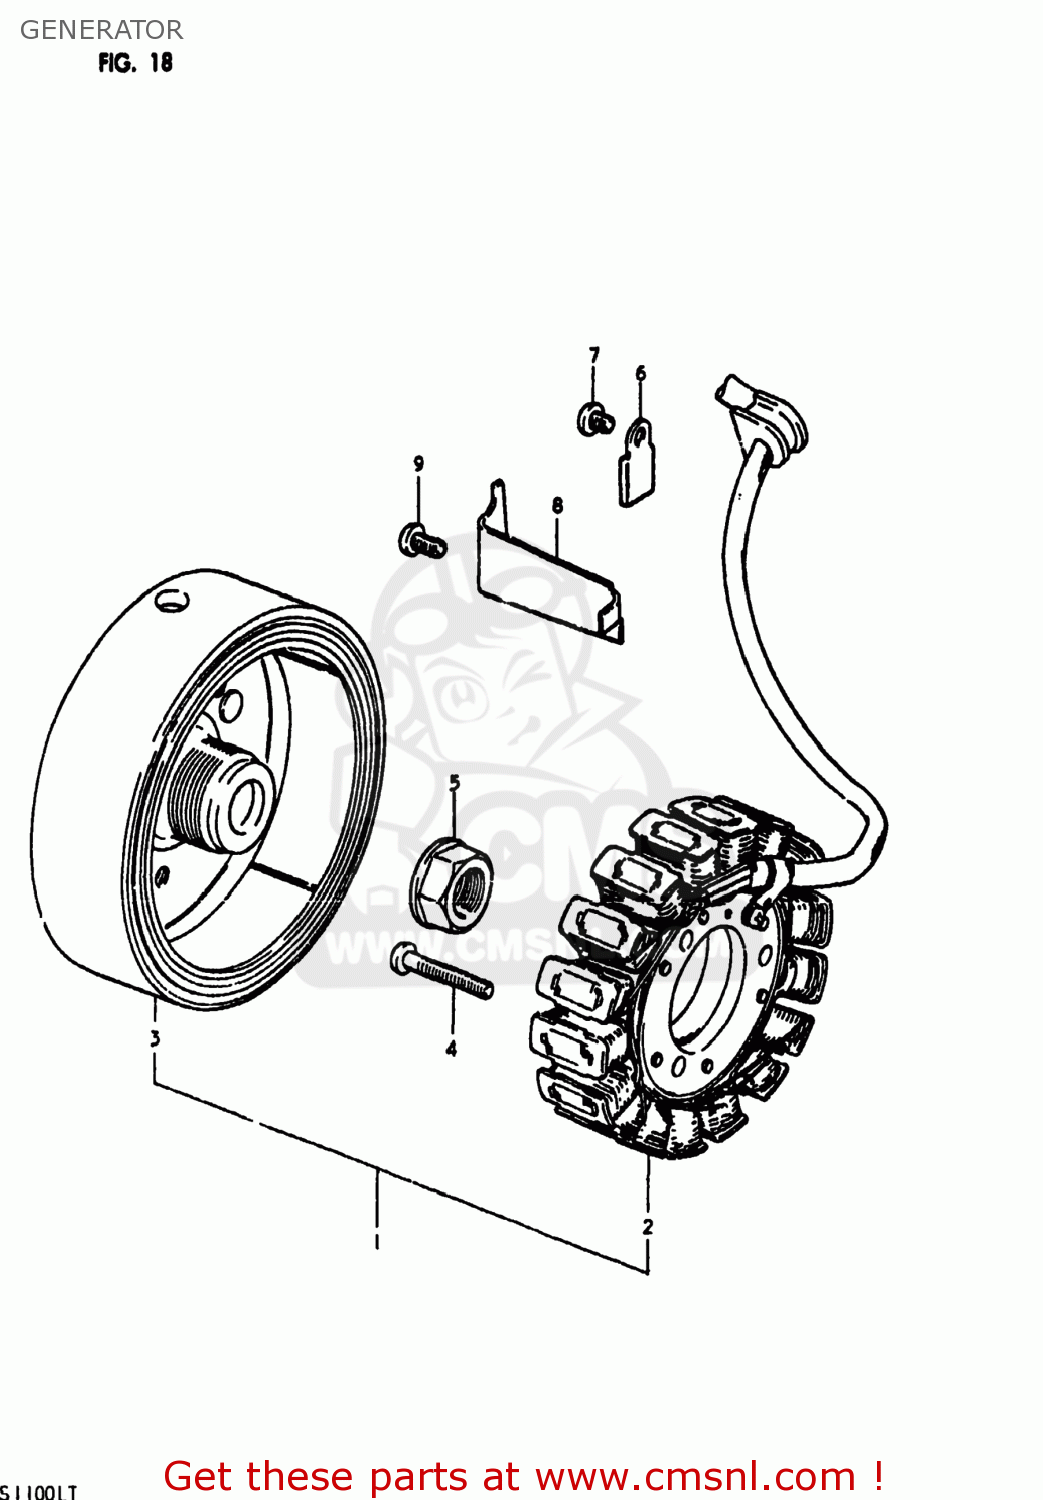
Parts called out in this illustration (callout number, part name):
1	GENERATOR ASSEMBLY
2	STATOR ASSEMBLY
3	ROTOR ASSEMBLY
4	SCREW 6X30
5	NUT,GENERATOR ROTOR
6	CLAMP,GENERATOR LEAD WIRE
7	SCREW
8	CLAMP,GENERATOR LEAD WIRE
9	SCREW
